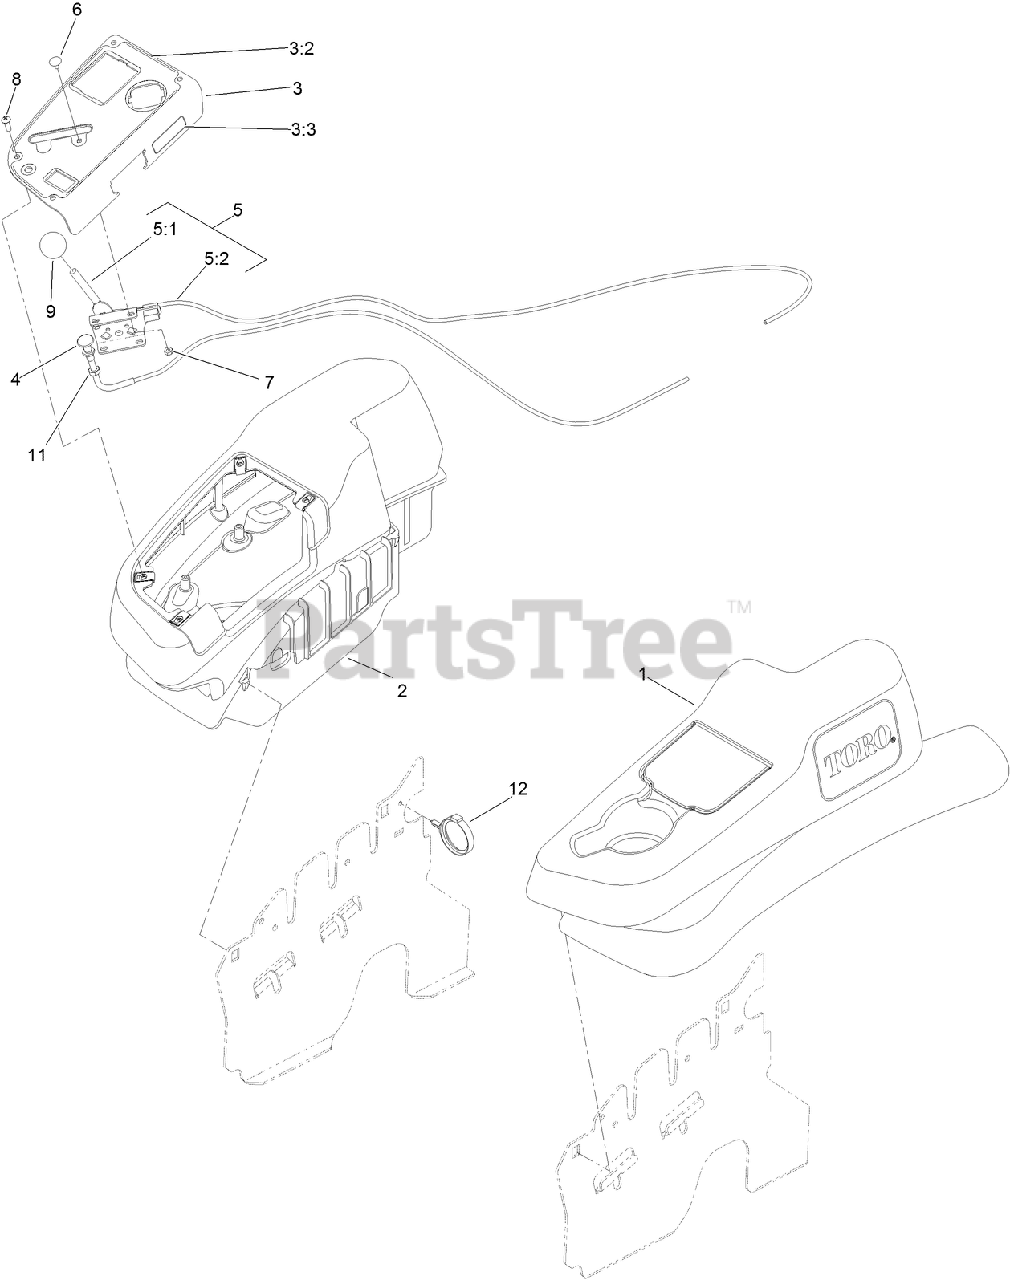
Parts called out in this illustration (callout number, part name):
1	LH NARROW FENDER/CONSOLE ASM
1	CONSOLE-LH
2	RH NARROW FENDER/CONSOLE ASM
3	CONTROL PANEL ASM
3:2	DECAL-CONTROL PANEL
3:3	DECAL-FUSES
4	CONTROL-CHOKE
5	THROTTLE CONTROL ASM
5:1	LEVER-THROTTLE
5:2	CABLE-THROTTLE
6	BOLT-CARR
7	NUT-LOCK, NI
8	SCREW-HWH
9	KNOB-BALL
11	NUT-HJ
12	CLAMP-HARNESS
